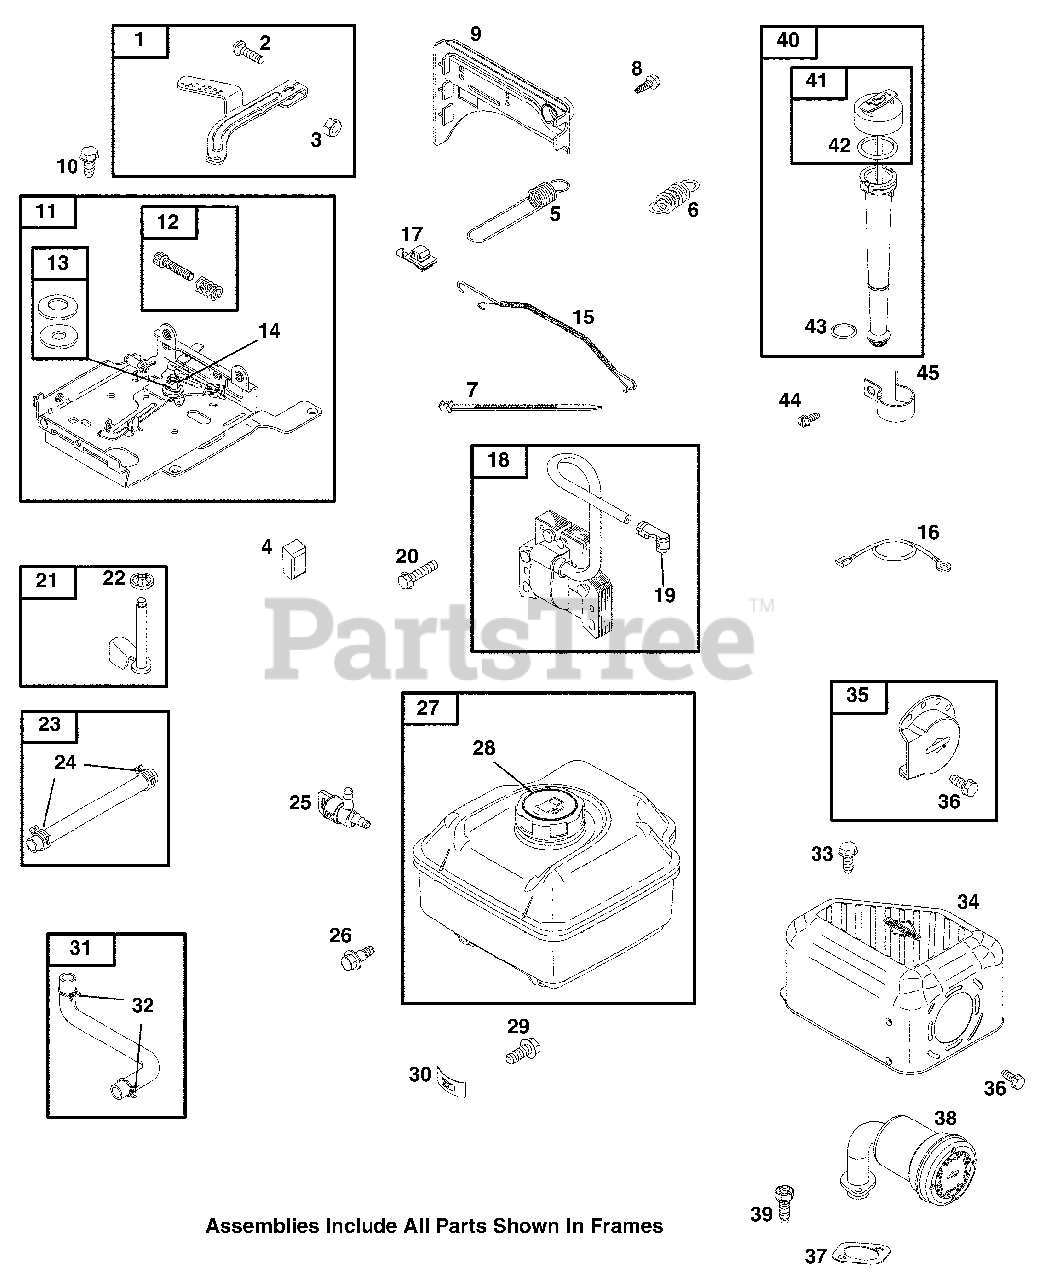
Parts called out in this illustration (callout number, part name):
1	Governor Lever
2	Bolt
3	Nut
4	Control Knob
5	Governor Spring
6	Governor Spring
8	Screw
9	Control Panel
10	Screw
11	Control Bracket
12	Idle Speed Kit
13	Washer Set
14	Nut
15	Spring/Link (Mechanical Governor)
17	Switch-Stop
18	Armature-Magneto
19	Sparkplug Terminal
20	Screw
21	Crank-Governor
22	Retainer-Governor Shaft
23	Fuel Line
24	Clamp-Hose
25	Valve-Shutoff
26	Screw
27	Fuel Tank
28	Fuel Tank Cap
29	Screw
31	Fuel Line (Molded)
32	Clamp-Hose
33	Screw
34	Guard-Muffler
35	Deflector-Muffler
36	Screw
37	Gasket-Exhaust
38	Muffler-Exhaust
39	Screw
40	Dipstick/Tube Assembly
42	O-Ring Seal (Dipstick)
43	O-Ring Seal
44	Screw
45	Oil Fill Bracket
